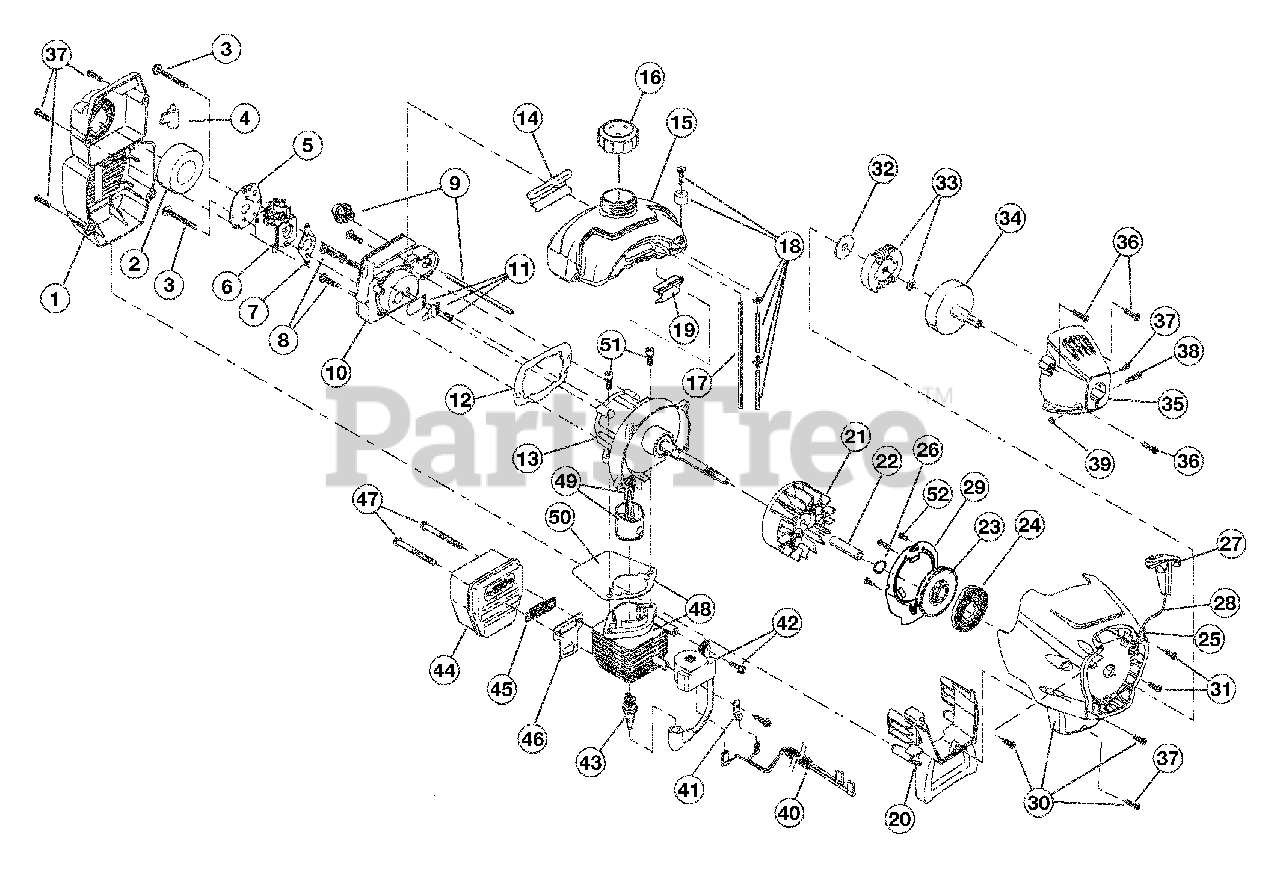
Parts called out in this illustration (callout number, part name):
1	Air Cleaner/Muffler Cover Assembly
2	Air Cleaner Filter
3	Carburetor Mounting Screw Assembly
4	Choke Extension
5	Choke Plate
6	Carburetor Assembly (includes 7 & 18)
7	Carburetor Gasket
8	Carb Mount Screw
9	Primer and Hose Assembly
10	Carb Mount Assembly (includes 8, 11& 12)
11	Reed Assembly
12	Carburetor Mount Gasket
13	Crank Case Service Assembly includes 8)
14	Rear Mounting Pad
15	Fuel Tank Assembly (includes 16-18)
16	Fuel Cap Assembly
17	Fuel Return Line
18	Fuel Line Assembly
19	Front Mounting Pad
20	Shroud Extension & Stand (includes 36)
21	Flywheel Assembly
23	Recoil Pulley
24	Recoil Spring
25	Rope Guide
26	Pulley Retainer
27	Pull Handle
29	Pressure Plate Assembly (includes 36)
30	Starter Housing Assembly
31	Housing Screw
32	Clutch Washer
33	Clutch Rotor Assembly
34	Clutch Drum Assembly
35	Clutch Cover Assembly (includes 36-39)
36	Cover Screw
37	Anti-Rotation Screw
38	Clamping Screw
39	Clamping Nut
40	Wire Leads and Sleeve
41	Ground Tab
42	Module Assembly (includes 41)
43	Spark Plug
44	Muffler Assembly (includes 45-47)
45	Spark Arrestor Screen
46	Exhaust Gasket
47	Muffler Mounting Bolt Assembly
48	Cylinder Assembly (includes 50 & 51)
49	Piston and Rod Assembly
50	Cylinder Gasket
51	Cylinder Bolt
52	Screw
